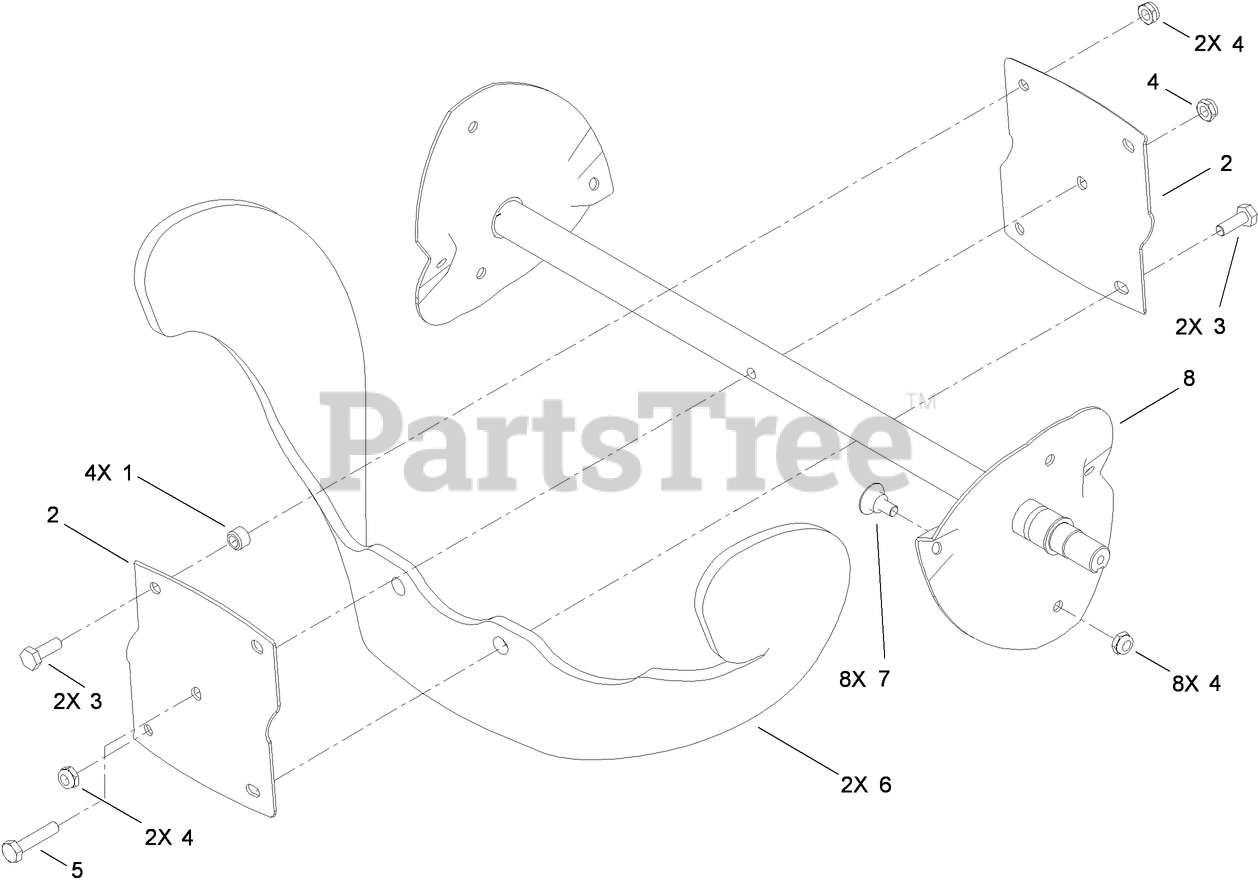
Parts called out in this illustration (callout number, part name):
1	SPACER-BLADE, ROTOR
2	HALF-ROTOR
3	SCREW-HH
4	NUT-LOCK, NI
5	SCREW-HH
6	BLADE-ROTOR
7	SCREW
